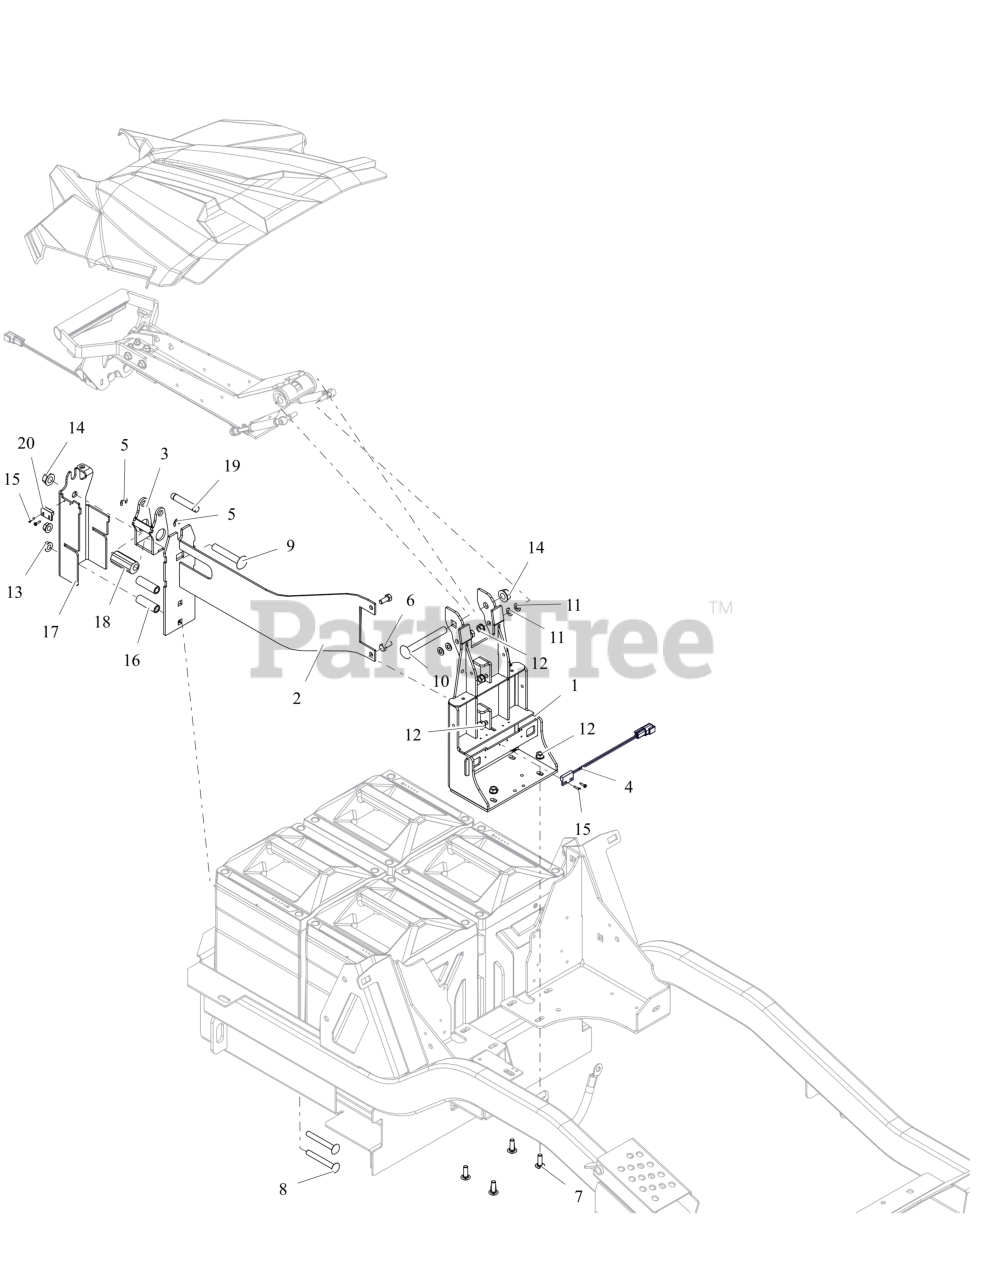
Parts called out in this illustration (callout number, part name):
1	WLDMT, BATTERY HOLDDOWN PIVOT (RED)
2	WLDMT, ECCENTRIC MTG (RED)
3	WLDMT, ECCENTRIC (BLACK)
4	SWITCH, MAGNETIC
5	RG-RTNG-EXT .438X.035
6	BLT,HEX .31-18X.75 G5 ZCC
7	BLT,RHSSN .31-18X1.00 G5 ZCC
8	BTL,RHSSN .375-16 X 3 G5 ZCC
9	BTL,RHSSN .500-13 X 3 G5 ZCC
10	BTL,RHSSN .500-13X 4.0 G5 ZCC
11	WSHR,FLT .323X.625X.062 ZCC
12	NUT,LK-CTR-FLG .31-18 GF ZCC
13	NUT-LK-CTR-FLG .375-16 GF ZCC
14	NUT-LK-CTR-FLG .500-13 GG ZCC
15	SCR-TAP #4-40X.50 HWH ZCC
16	SPCR, LATCH BRKT (BLACK)
17	BRKT, ECCENTRIC MTG (RED)
18	ECCENTRIC, HOOD LATCH
19	ROD, LATCHING
20	SWITCH, MAGNET (NO WIRE)
